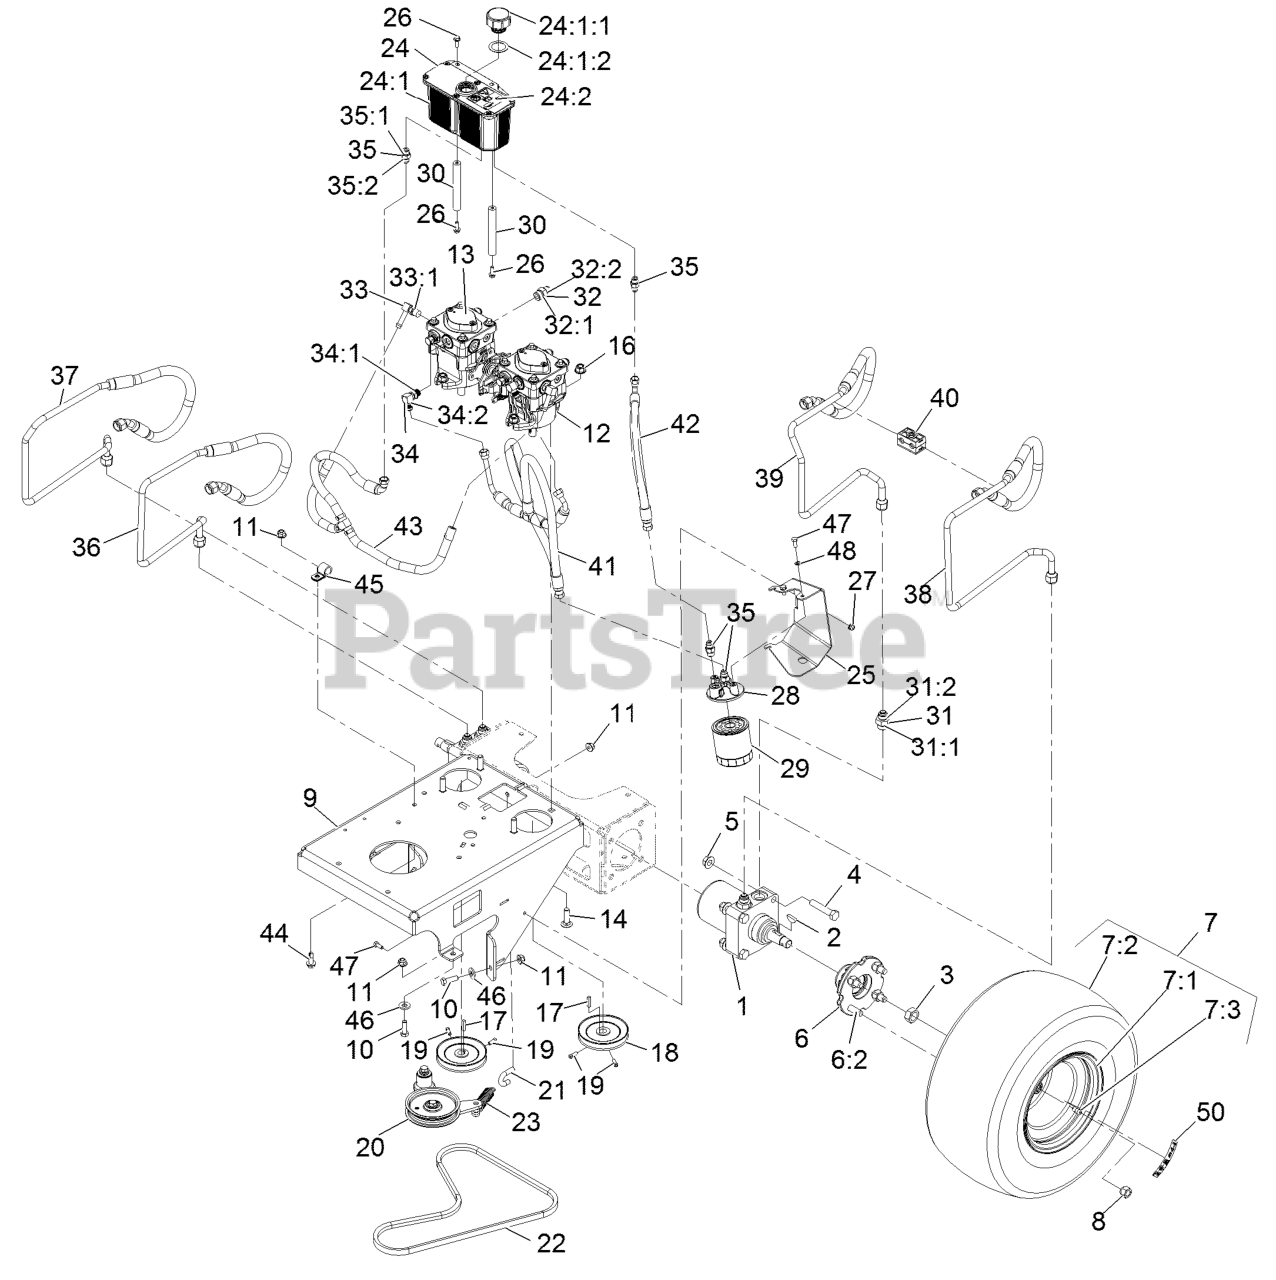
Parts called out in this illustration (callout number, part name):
1	HYD MOTOR ASM
2	KEY-WOODRUFF
3	NUT-MOTOR, WHEEL
4	SCREW-HH
6	WHEEL HUB ASM
6:2	STUD-TYPE, DRIVE
7	WHEEL/TIRE ASM
7:1	RIM-8 INCH
7:3	Stem-Valve
8	NUT-LUG
9	BASE, ENGINE
10	SCREW-HH
11	NUT-HF, NI
12	PUMP - HYDRAULIC
13	PUMP-HYDRAULIC
14	SCREW-HH
16	NUT-HF, NI
18	PULLEY-PUMP
19	SCREW-SET
20	PUMP IDLER ASM
21	ANCHOR, SPRING
22	BELT-V
23	SPRING-EXTENSION
24	RESERVOIR ASM
24:1	Reservoir-Hyd
24:1:1	Cap-Reservoir, HYD
24:1:2	GASKET-CAP
24:2	DECAL-WARNING
25	PLATE-FILTER MOUNT
26	SCREW-HHF
28	HEAD-FILTER
29	FILTER-25 MICRON, BI-DIRE
30	ROD-RESERVOIR STAND
31	FITTING-STRAIGHT
31:1	O-RING
32	FITTING-STRAIGHT
33	FITTING-ELBOW, 90
33:1	O-RING
34	FITTING-90 DEG
35	FITTING-STRAIGHT
36	HOSE-HARDLINE
37	HOSE-HARDLINE
38	HOSE-HARDLINE
39	HOSE-HARDLINE
40	CLAMP, STAUFF 212,7/12,7
41	HOSE-ASM CHARGE
42	HOSE ASM-HYD LP 3/8X14.4
43	HOSE ASM - HYD 3/8
44	SCREW-TAPPING
45	CLIP-LOOM
46	WASHER-BELLEVILLE
47	SCREW-HH
48	WASHER-LOCK
50	DECAL-WHEEL TORQUE
